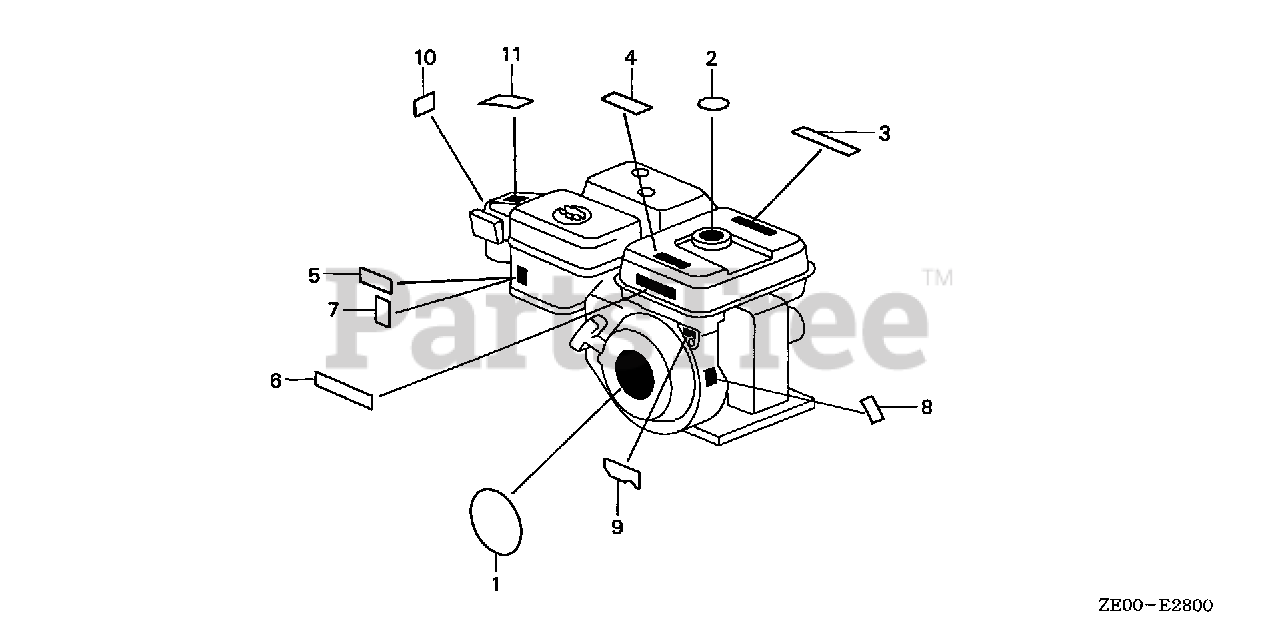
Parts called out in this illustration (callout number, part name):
1	EMBLEM (EXTERNAL/ALERT)
2	MARK, CAUTION
7	MARK, CHOKE
9	MARK, OIL ALERT (EXTERNAL) (NOT AVAILABLE)
